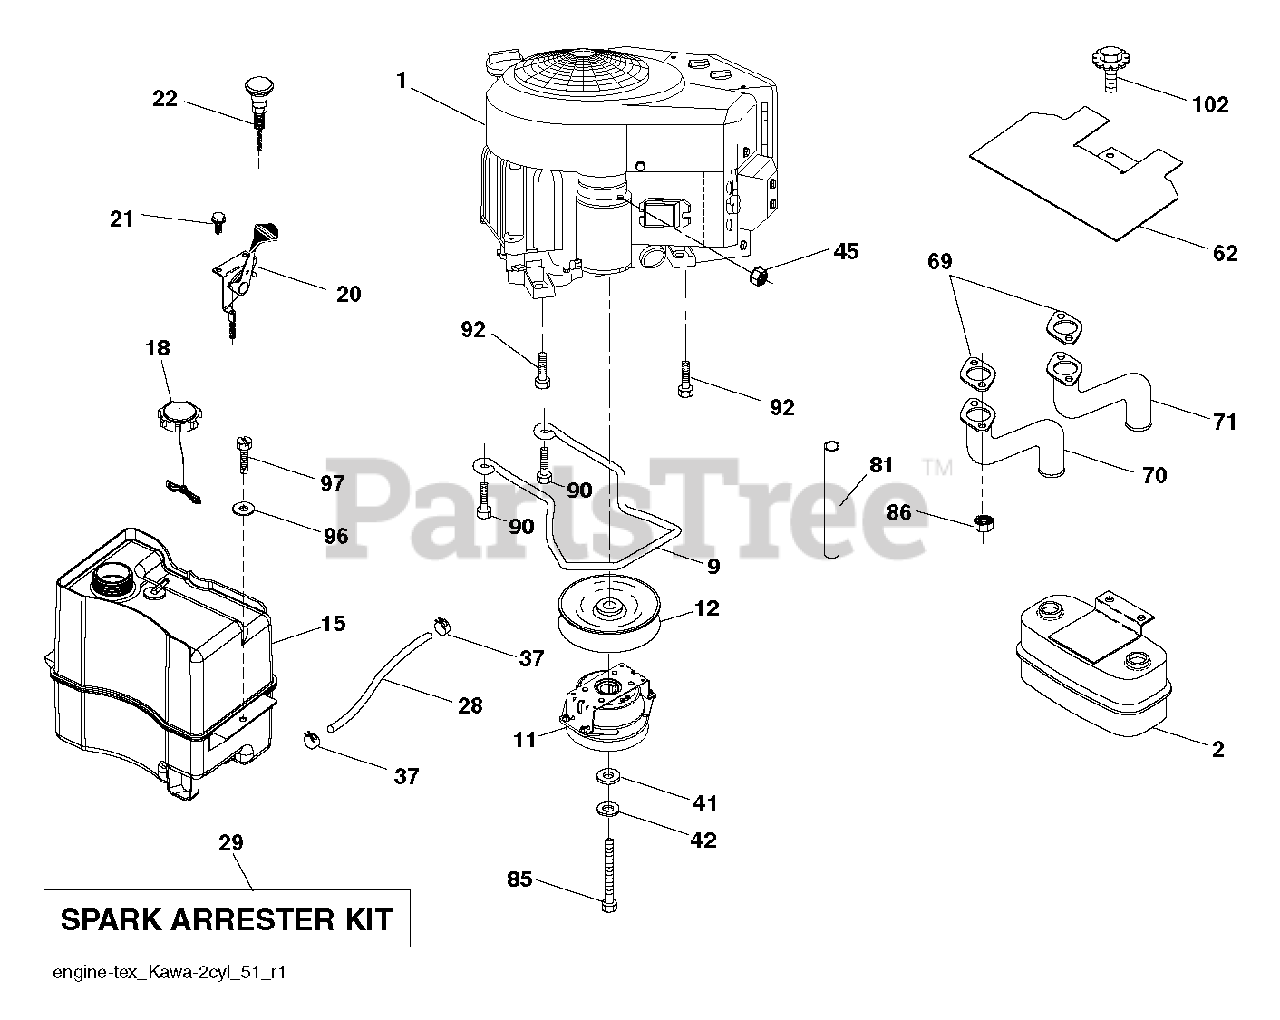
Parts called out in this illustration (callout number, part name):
2	MUFFLER.ASM.TWN.EXTNDED.DFLCTR
9	KEEPER.BELT.ENG.4.25"2.BLT.431
11	CLUTCH.OGURA.5.0PD.GT1.5A-EH07
12	PULLEY.ENGINE.TUFFTORQ
15	TANK.ASSEMBL.2.5GAL.NON-EPA
18	CAP ASM.FUEL.2.25"FR.
20	CONTROL.THROTTLE.COBRA.BLACK
21	SCREW.#10 X 0.750.BOS
22	CONTROL.CHOKE.ERGO.BLACK
28	LINE.FUEL.20
29	KIT.SPARK ARRESTOR 794945 B&S
37	HOSE CLAMP
42	LOCKWASHER
45	NUT
62	SHIELD.HEAT.MUFFLER
70	TUBE.EXHAUST.RH.FR961/FR730
71	TUBE.EXHAUST.LH.FR961/FR730
81	TUBE, DRAIN OIL ASM.
85	BOLT.HEX.7/16-20X3.75.GR5.RED
86	BLADE ADAPTER
90	SCREW 3/8-16X1
92	SCREW 3/8-16X1
97	SCREW HEXWSHR 1/4-20X3/4
102	SCREW
